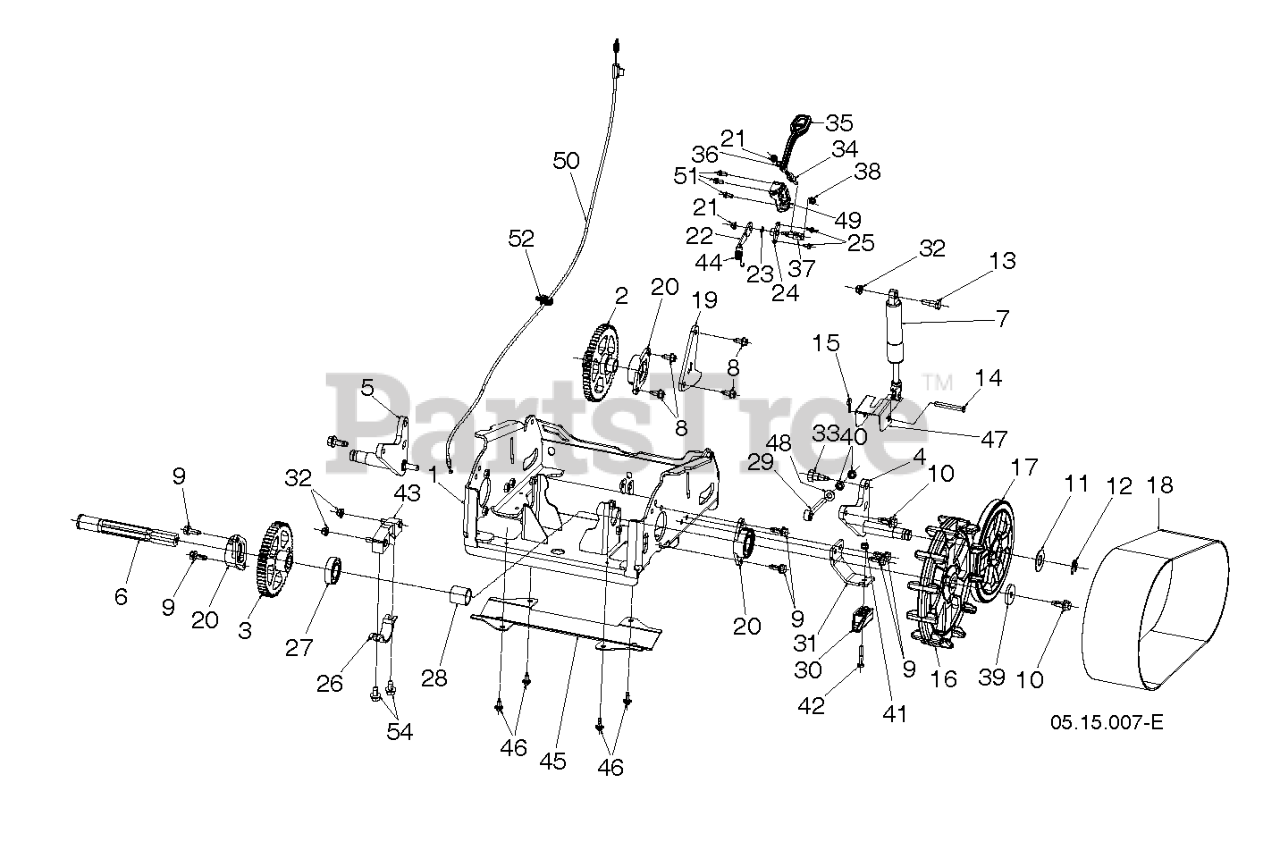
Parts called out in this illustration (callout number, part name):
2	GEAR TRACK TRANSMISSION
3	GEAR TRACK
4	ARM TRACK ADJUSTER WELDMENT LH
5	ARM TRACK ADJUSTER WELDMENT RH
6	AXLE TRACK HEX
8	BOLT.HEX.HD.WASHER.5/16-18X.75
9	SCREW HEXAGON HEAD FLANGE 5/16
10	SCREW HEXAGON HEAD FLANGE 3/8-
11	WASHER.HARDENED
13	BOLT SHOULDER 10MM
15	RETAINER M
20	CARRIER BEARING
21	NUT HEX; NYLON LOCKING; FLANGE
23	WASHER WAVE 3/8
24	BUSHING BUCKET HEIGHT ADJUSTER
26	MOUNT BEARING
27	BEARING SEALED R16-2RS
28	SPACER TRACK AXLE
29	ROD END SOLID, 3/8
32	NUT HEXAGON FLANGE 5/16-18 ST
34	ROD LEVER CONTROL
36	DISC SPRING
37	AXLE BUCKET HEIGHT CONTROL
38	NUT HEXAGON 1/4-20 ST ZPB
39	SPACER PLATE .38 X 1.5
40	NUT NUT.3/8-16.HEX.JAM.Z 3/8-1
41	NUT FLG, NYLOCK, 1/4-20 GR G C
42	Bolt Hex Fin 1/4-20 Unc x 1-1/2
43	BEARING MOUNT
44	SPRING EXTENSION - DRIVE
46	HEX.WASHER.HEAD 1/4-20 X .65
48	WASHER PLAIN WASHER 3/8 X 0.08
49	BRACKET BUCKET HEIGHT LEVER BU
50	CABLE ASSY BUCKET HEIGHT ADJUS
51	SCREW.HWH.13-16X.50
52	CABLE, 1/4 BLACK FIR TREE
